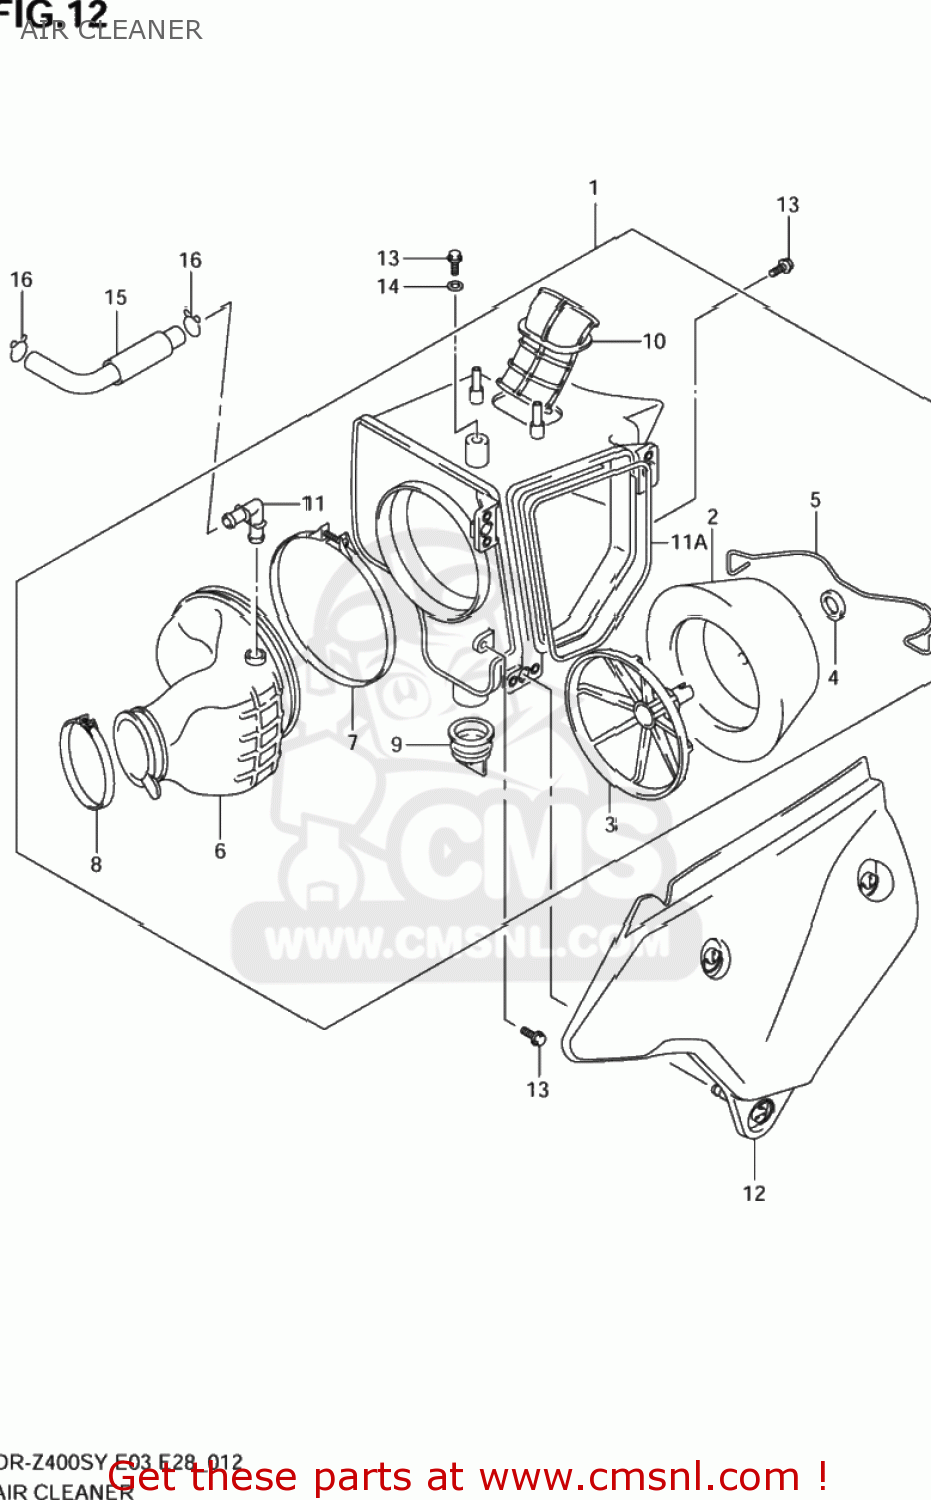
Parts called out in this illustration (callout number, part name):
1	CLEANER,AIR
2	FILTER ASSY
3	HOLDER,FILTER
4	SPACER
5	SPRING
6	TUBE,OUTLET
7	CLAMP
8	CLAMP
9	VALVE
10	TUBE,INLET
11	JOINT
11A	GASKET,AIR CLEANER (NAS)
12	CAP,AIR CLEANER
13	BOLT
14	WASHER
15	TUBE COMP,BREATHER
16	CLIP
